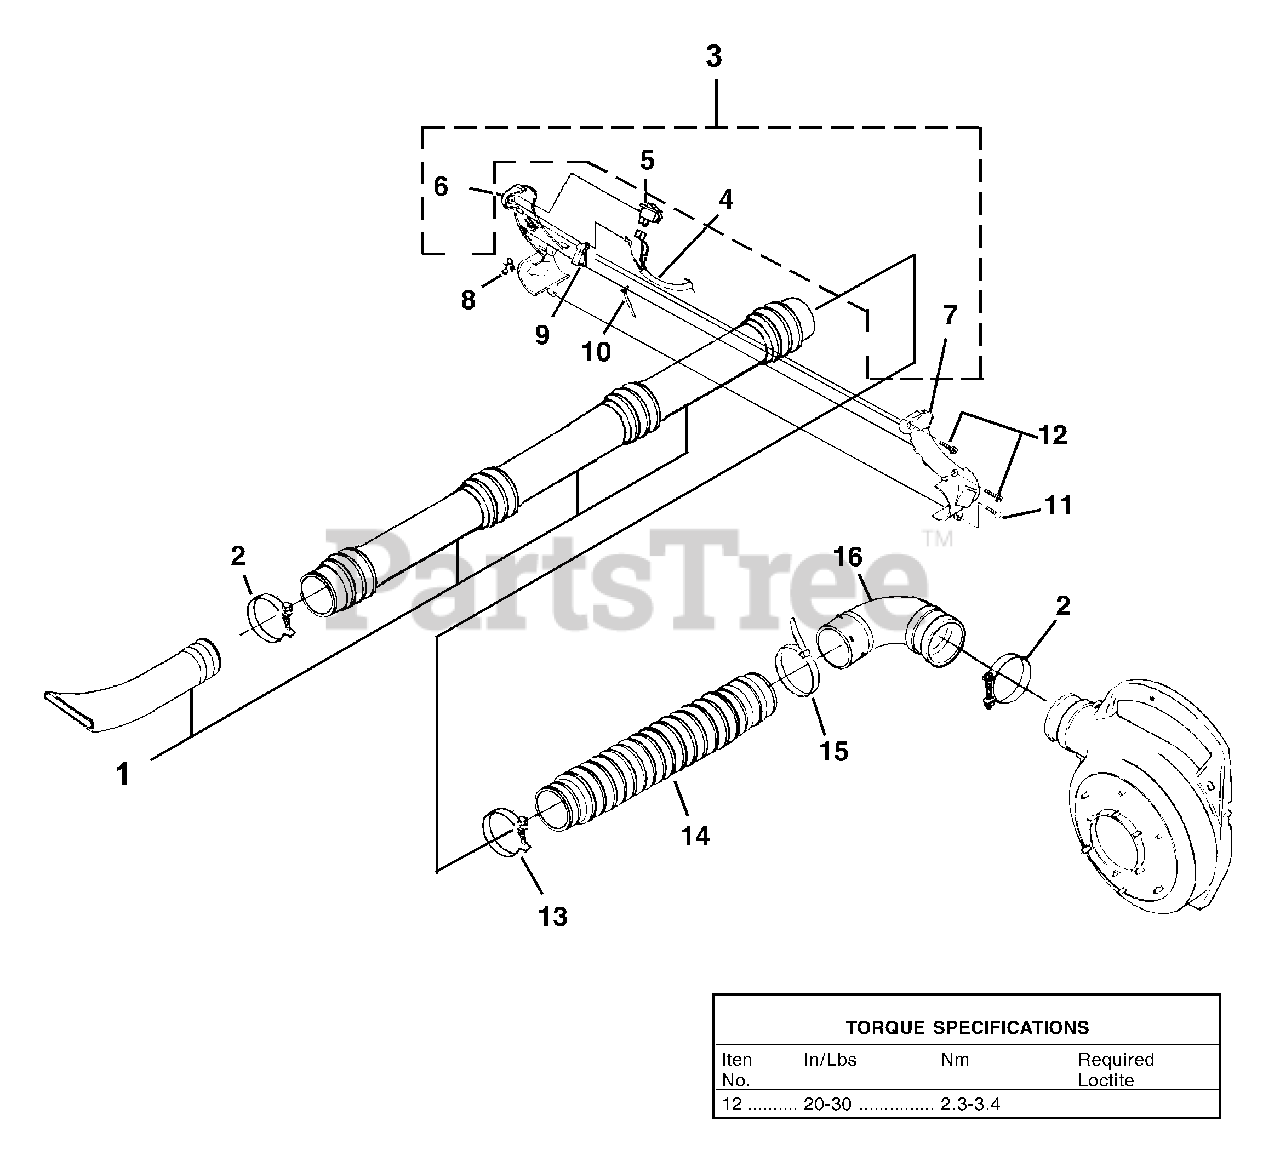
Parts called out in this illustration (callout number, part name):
1	BLOWER TUBE KIT
2	CLAMP
3	HANDLE & SWITCH KIT
4	CABLE-Throttle w/ Ignition Leads
6	HANDLE-Control (Right)
7	HANDLE-Control (Left)
8	NUT - Wing (10-24)
9	TRIGGER
10	LATCH-Trigger
11	BOLT-Rib Neck, Rnd. Hd. (10-24 X 7/8")
12	SCREW-Thread Form. (10-14 X 3/4")
13	CLAMP (#87)
14	BELLOWS-Plastic
15	CABLE-Tie
16	ELBOW-Curved
